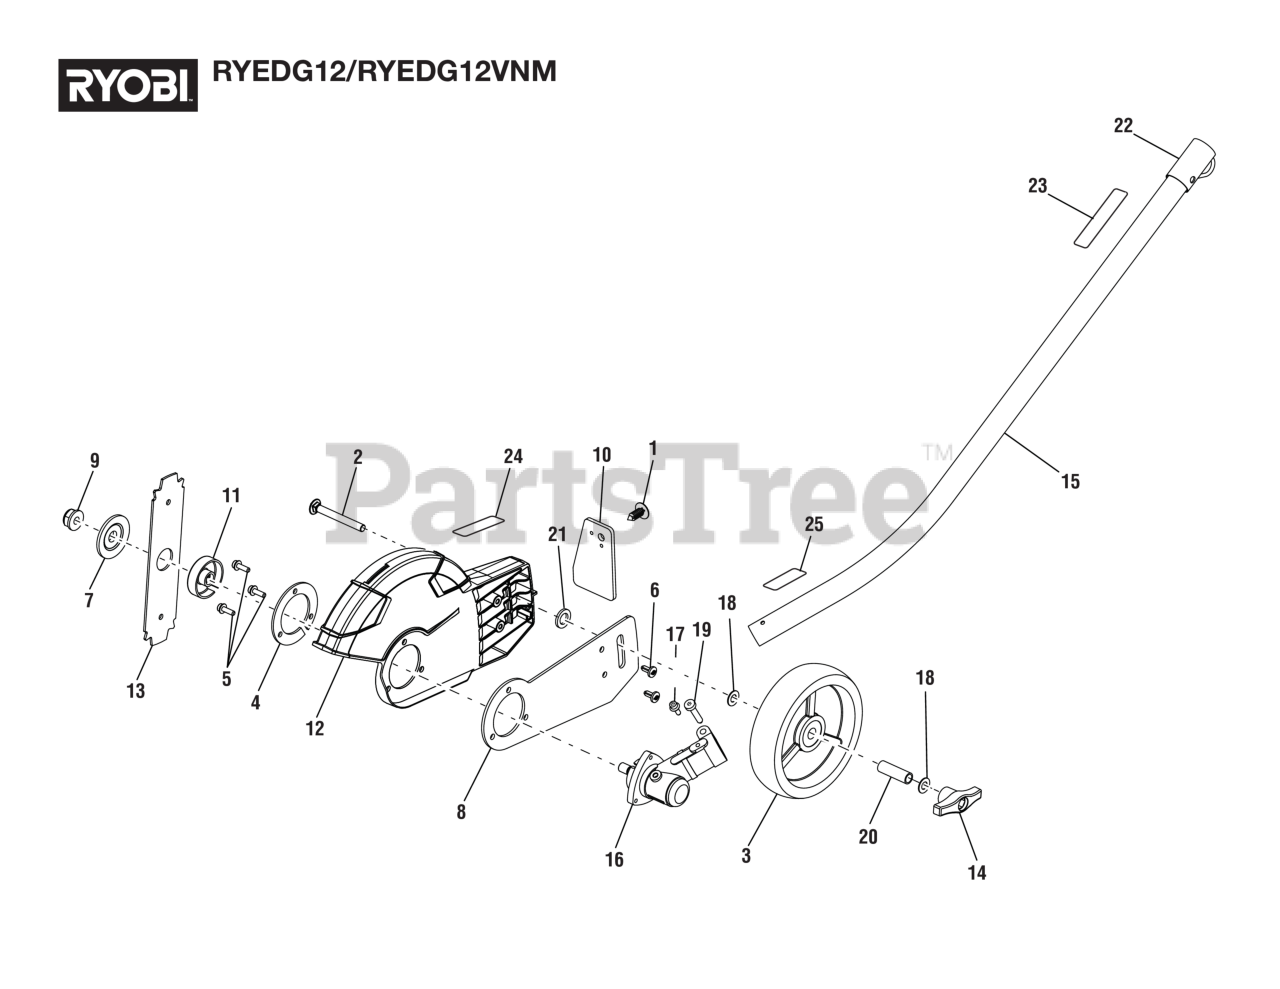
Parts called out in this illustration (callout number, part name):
1	Trim Clip
2	Carriage Bolt (M8 x 1.25 in.)
3	Wheel (dia150 mm)
4	Mounting Ring
5	Screw (M5 x 16 mm, T25 Torx Soc. Hd.)
6	Vacuum Tube Screw (10-14 x 1/2 in., T25 Torx Truss Hd. T.F.)
7	Blade Washer
8	Main Bracket
9	Blade Lock Nut (M10 x 1.25 in.)
11	Flange Washer
12	Grass Shield Assembly
13	Blade (8 in., AC04215)
14	Adjusting Knob w/Hex Nut
15	Boom Assembly
16	Gear Case Assembly
17	Screw (10-24 x 5/8 in. Hex Socket Hd.)
18	Washer (ID8.5 x OD20.5 x 2 mm x 2t)
19	Screw (1/4-20 x 1-1/4 in., Hex. Socket Hd.)
20	Axle Spacer
21	Washer (ID12 x OD20 x 2.5t)
22	Hanger Cap
23	Boom Icon Warning Label
24	Shield Icon Warning Label
25	Hot Surface Warning Label
